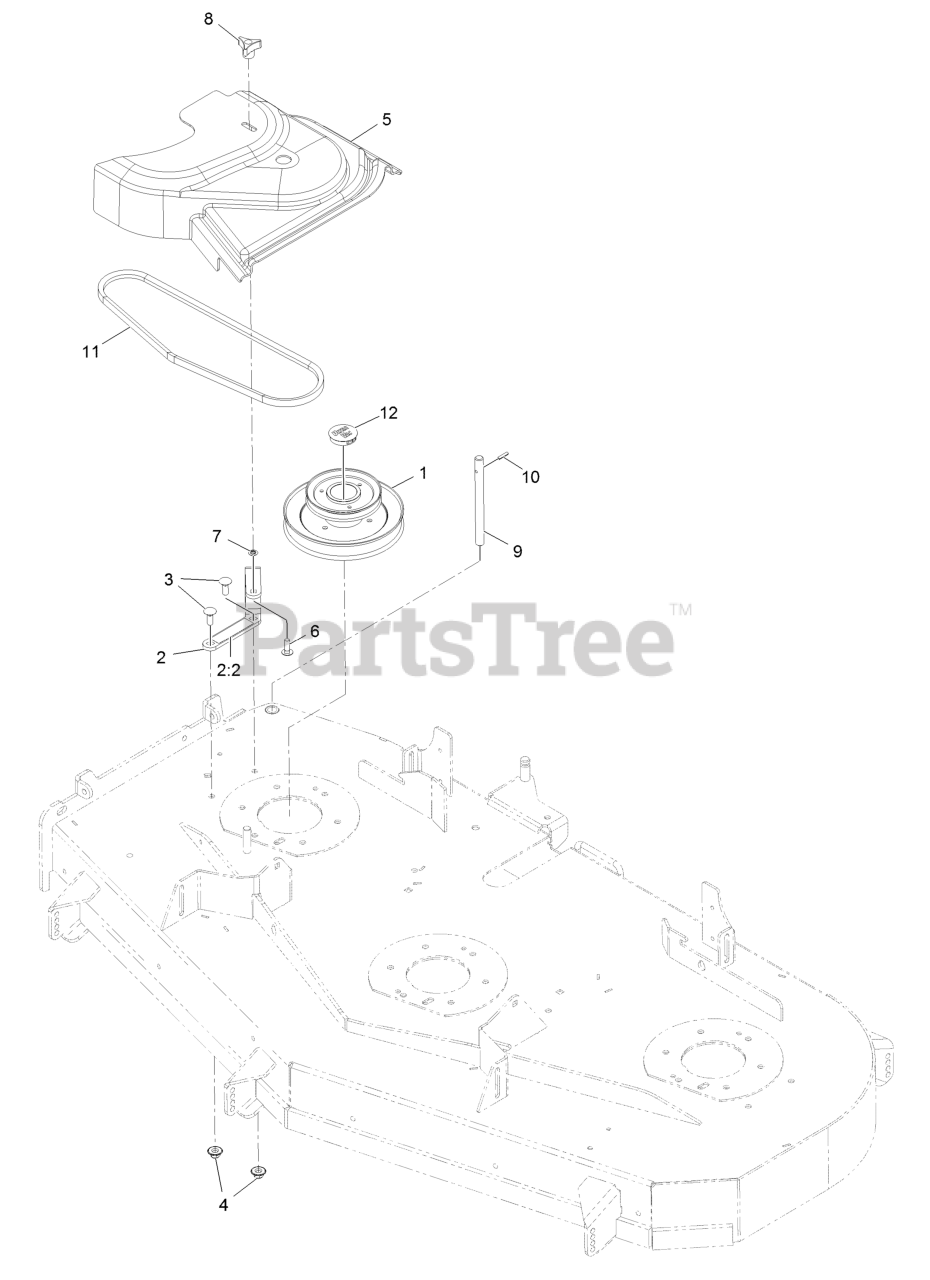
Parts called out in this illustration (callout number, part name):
1	Jackshft- Uv Drive 603
2	ASM-Cvr Brkt W/Decal
2:2	Decal-Cover, Missing
3	Bolt-Carriage 3/8-16 X 1
4	Nut-Nyloc 3/8-16 Flg
5	Cover-Belt Uve 60
6	Bolt-Carriage 5/16-18 X 1
7	Ring-Bolt Retaining
8	Knob-3 Prong
9	Shaft-Catcher, Grass
10	Rollpin 3/16 X 7/8
11	Belt,A 42.32
